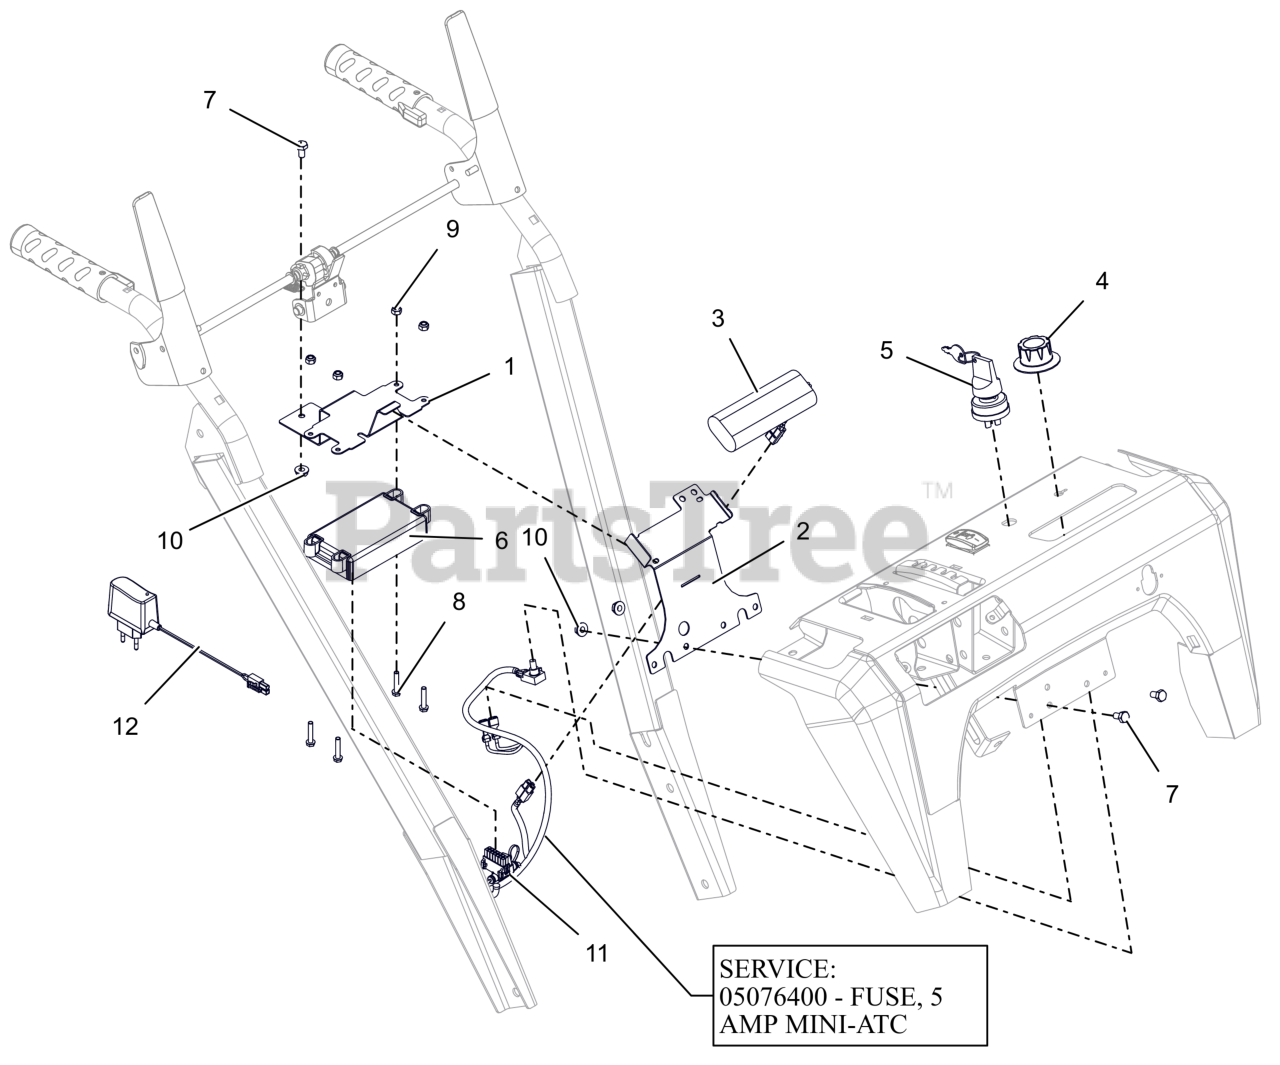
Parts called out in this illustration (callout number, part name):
1	BRACKET, ENGINE EFI-LCT LOWER
2	BRACKET, ENGINE EFI-LCT UPPER
3	BATTERY, SNOW EFI - 7.2V
4	KNOB, CONTROL - 2.063 ID
5	IGNITION SWITCH ASM - 2 POS
6	ECU SERVICE LCT/CSI - 420CC
7	BLT,HEX .25-20X.50 G5 ZCC
8	BLT, HWH #10-24X1.00 ZCC
9	NUT-LK-NYL #10-24 G2 ZCC
10	NUT-LK-TOP-FLG .250-20 GF ZCC
11	HARNESS,WIRE - EFI ECU
11	FUSE, 5 AMP MINI-ATC
12	CHARGER, BATTERY-EFI 7.2V (EU)
